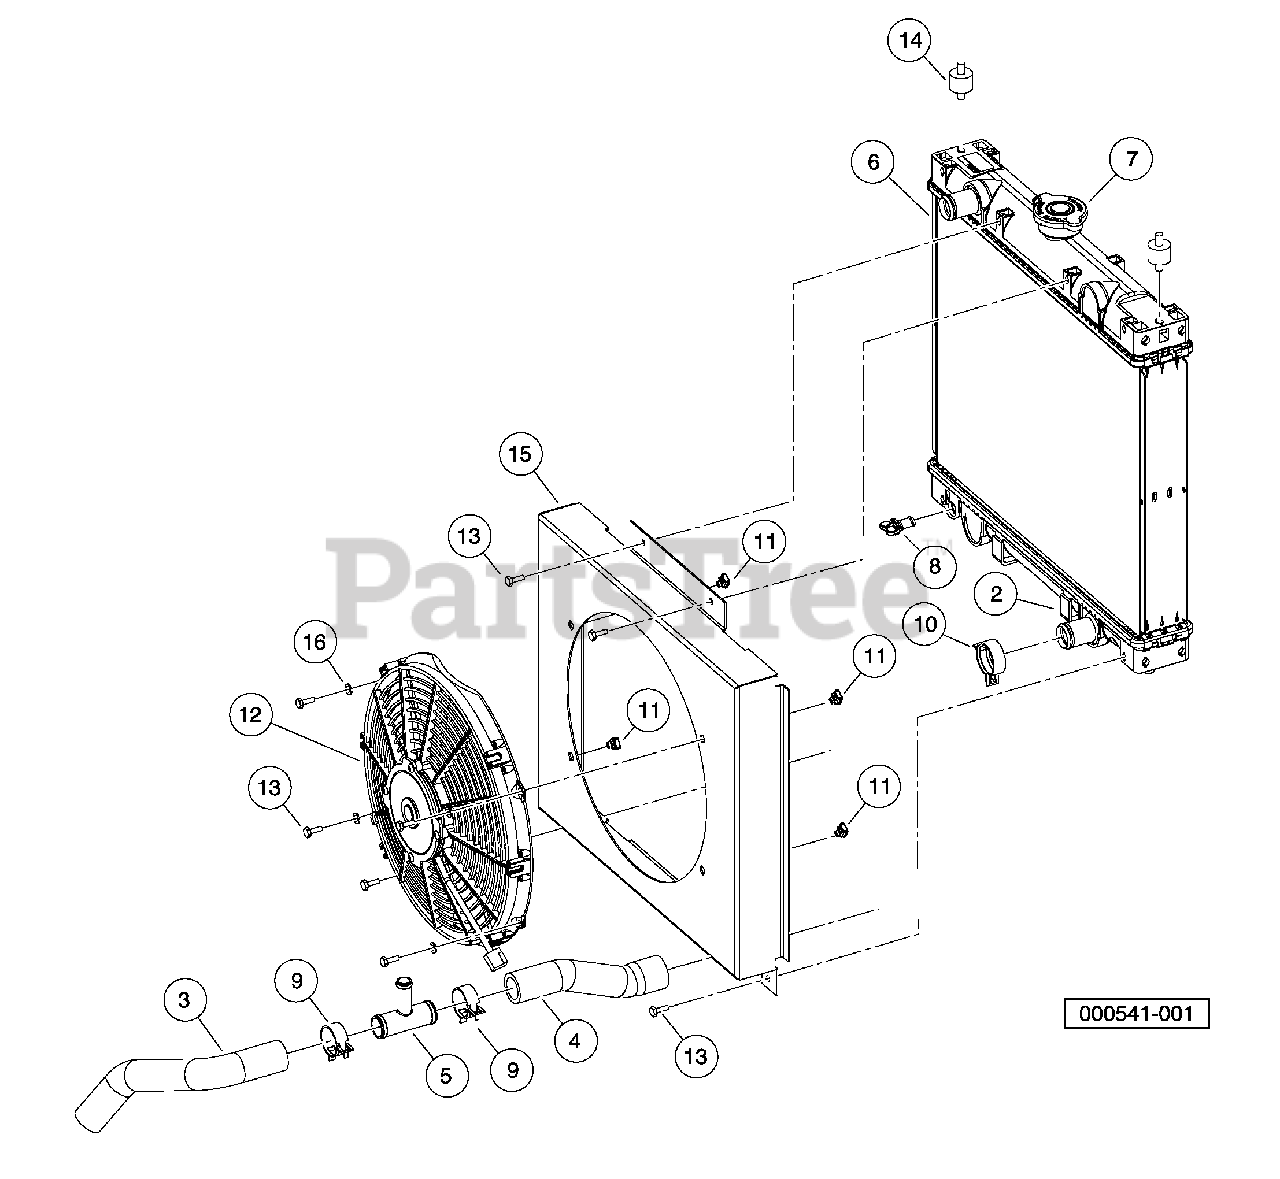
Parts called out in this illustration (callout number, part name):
1	Asm, Radiator
2	Tape, Vinyl Foam 1/8" x 3/4"
3	Hose, Coolant Lower Pipe
4	Hose, Coolant Lower Rad
5	Tee, Coolant Fill
6	Exchanger, Engine Coolant
7	Cap, Radiator
8	Drain Cock, Radiator
9	Clamp, Hose, Ctb 35mm
10	Clamp, Hose, Ctb 38mm
11	Nut, Self Retaining
12	Fan, Cooling 12 In Elect
13	Bolt, M6 X 1 X 16 Loctite
14	Isolator, Twin-Stud
15	Shroud, Radiator Fan
16	Washer, M6
